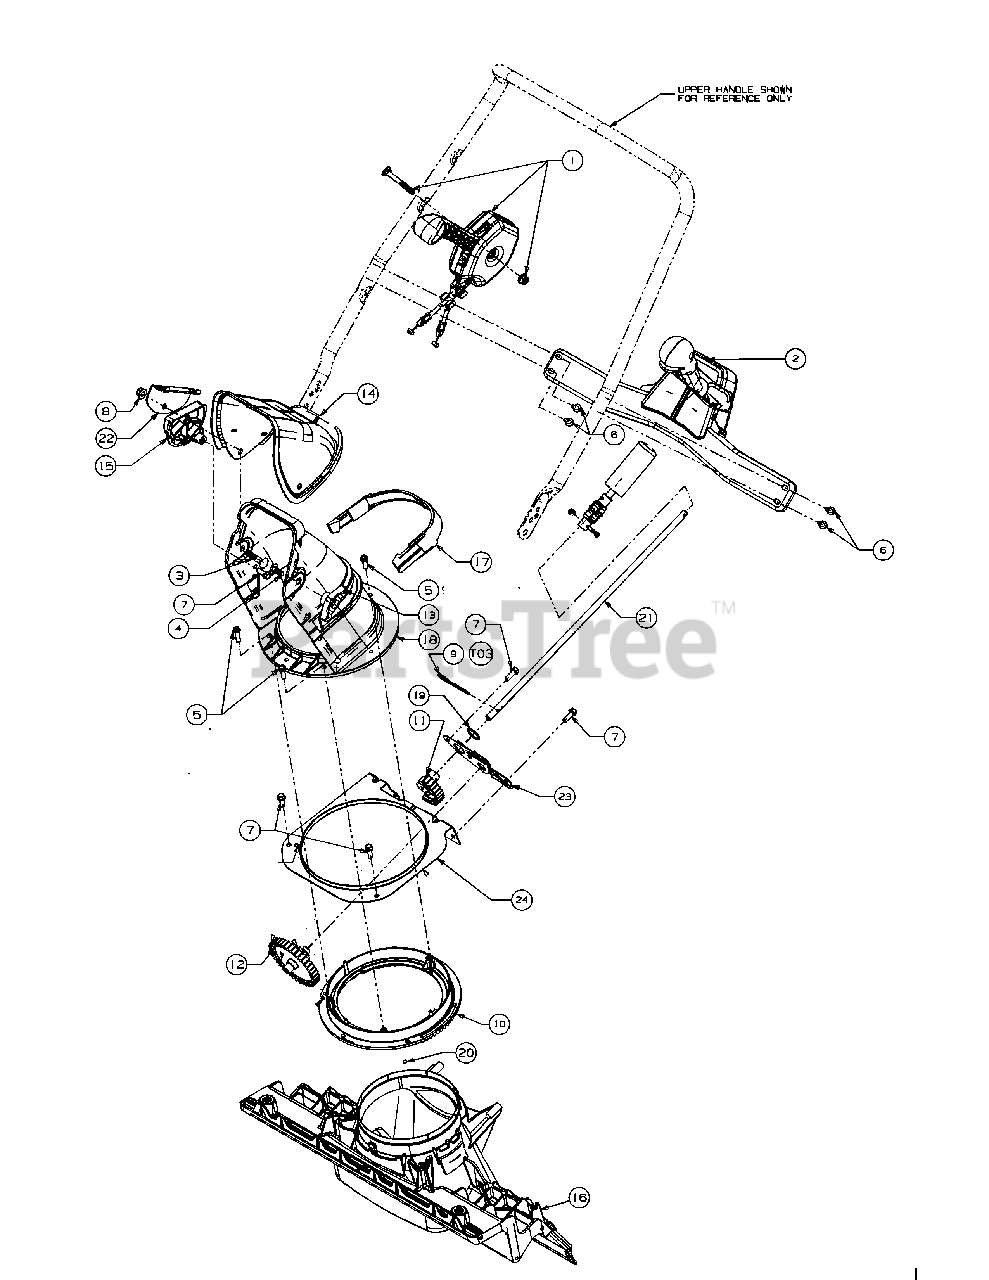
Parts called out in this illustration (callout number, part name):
1	Pnl Asm:Chute Tilt
1	Bolt-Crv Hd Crg
1	Nut-Flglk 5/16-18
1	Housing-Chute Control
1	Handle-Chute Tilt
1	Clip-Cable
1	Cable-2 Way Chute
1	Spacer .325X.496X
2	Handle Asm-Chute R
3	Bolt-Carriage 5/16
4	Carriage Bolt 5/16-18 X .75
5	Screw-Hex Indwsh B
6	Screw-Hex Wash Sf
7	Screw-Hex Tap 1/4
8	Nut-Flglk 5/16-18
9	Pin-Cotter .125X2.
10	Gear-Bevel 95T
11	Gear-Spur
12	Spur-Gear 40T
13	Knob-Wing 5/16-18
14	Chute-Upper:W/
15	Guide-Cable Chute
16	Adapter-Chute
17	Plug-Chute W/O
18	Chute-Lower
19	Washer-Flat .75X1
20	Grease
21	Rod-Chute Crank Lo
22	Bracket-Cable
23	Plate-Gear Mtg Chut
24	Bracket-Retain Gea
